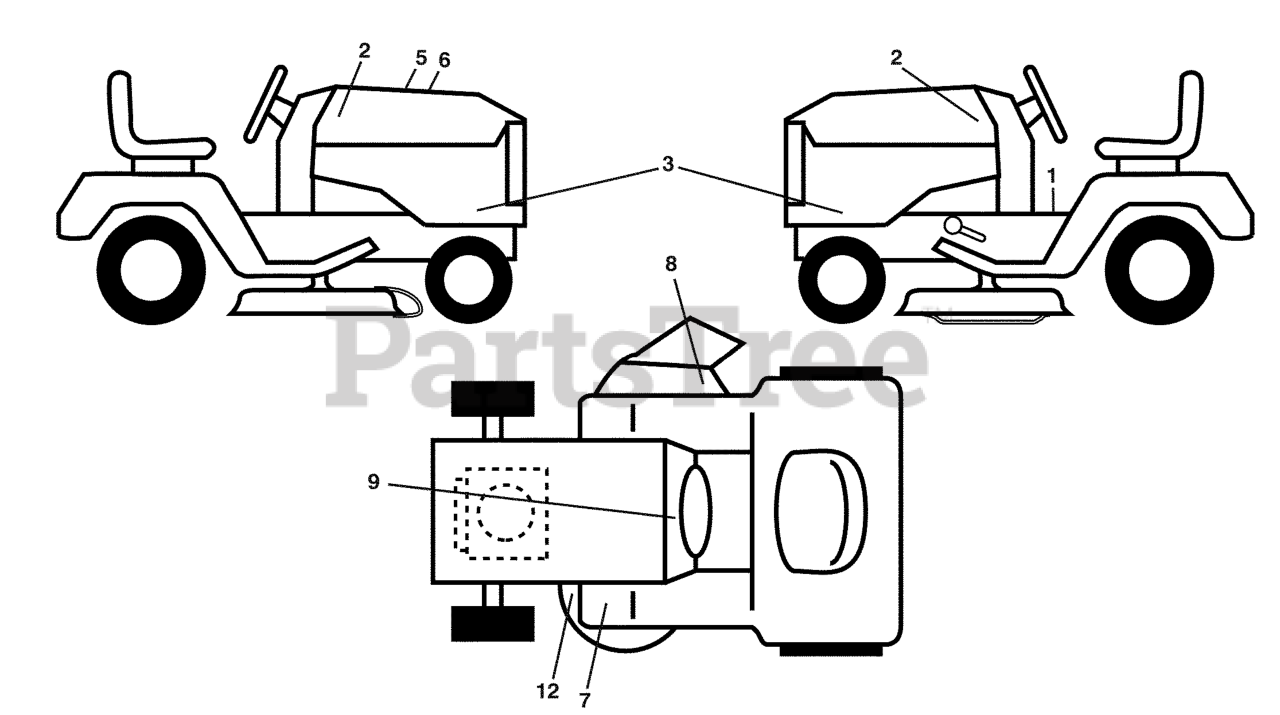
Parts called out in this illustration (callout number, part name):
1	DECAL.FENDER.WARNING.ENG
2	RP EMBLEM, HOOD
3	DECAL, EMBLEM PANEL SD
5	DECAL.WARNING.CUST.RESP.E85.
6	Decal, Replacement
7	DECAL.PEDAL.HUSQ.CROWN
8	DECAL.WARN.KEEP.HAND.AWAY
9	DECAL BTRY SYMBOLS
12	DECAL V BELT SCHEMATIC
